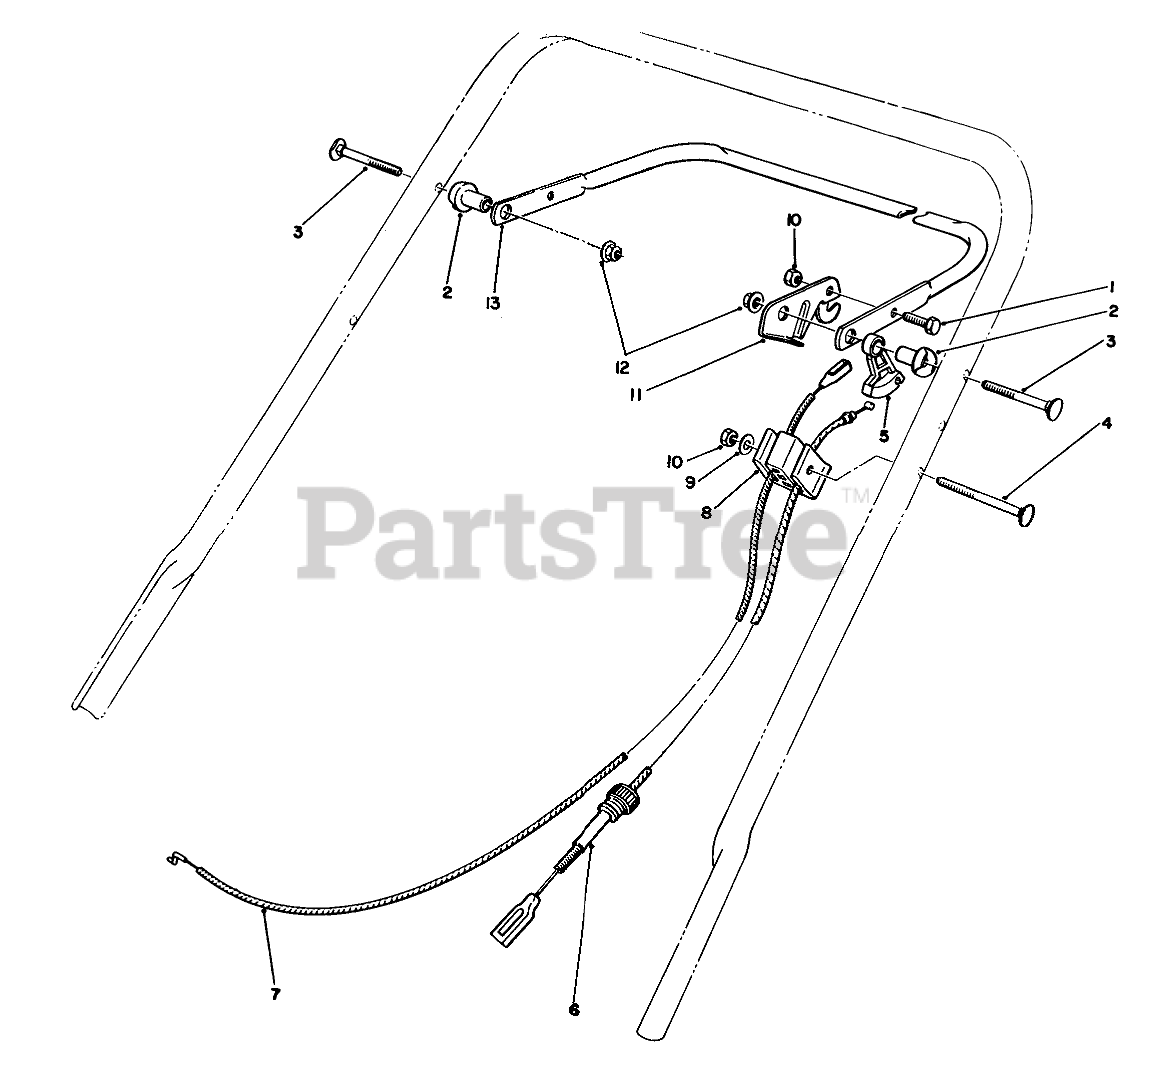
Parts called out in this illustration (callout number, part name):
1	SCREW-HH
2	SPACER-SUPPORT
3	5/16-18 X 2 HNDLE SCREW
4	HANDLE SCREW
5	LEVER-TRACTION
6	CABLE-TRACTION
7	BRAKE CONTROL
8	SUPPORT-CABLE
9	WASHER-FLAT
10	NUT-LOCK, NI
11	LEVER-CONTROL
12	NUT-LOCK, NI
13	Bar-Control
